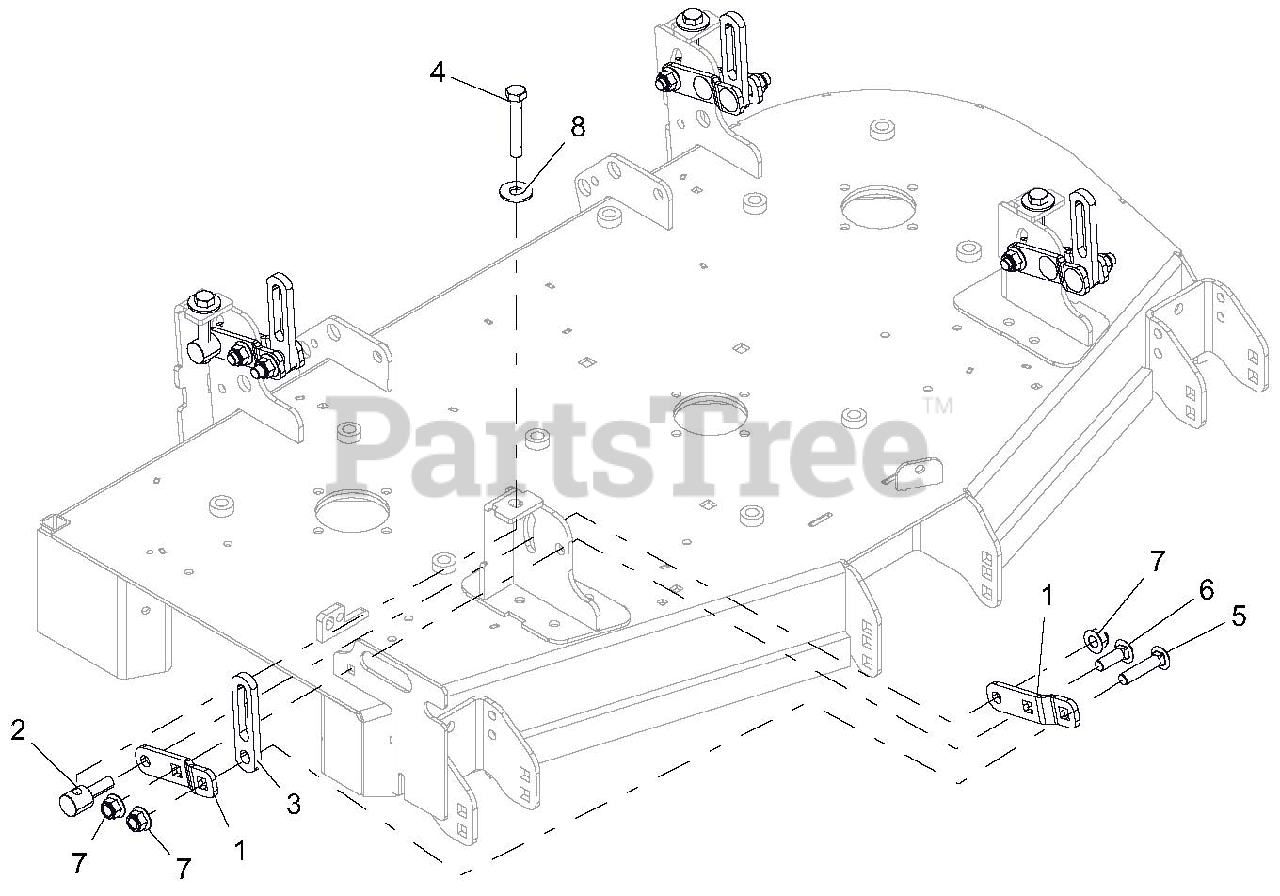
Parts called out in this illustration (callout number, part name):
1	BRKT, DECK LEVELING-BLACK
2	TRUNNION, .50-13
3	LINK, DECK LIFT - SHORT
4	BLT, HEX .500-13 X 3.000 GR5 FTH YZ W/NYLON PATCH
5	BLT-RDHDSQNK .50-13X2.25 G5 Y
6	BLT-RDHDSQNK .50-13X1.50 G5 YWZC
7	NUT-LK-NYL-FLG .50-13 YWZC
8	WSHR-FL-STL.563X1.38X.109YWZC
